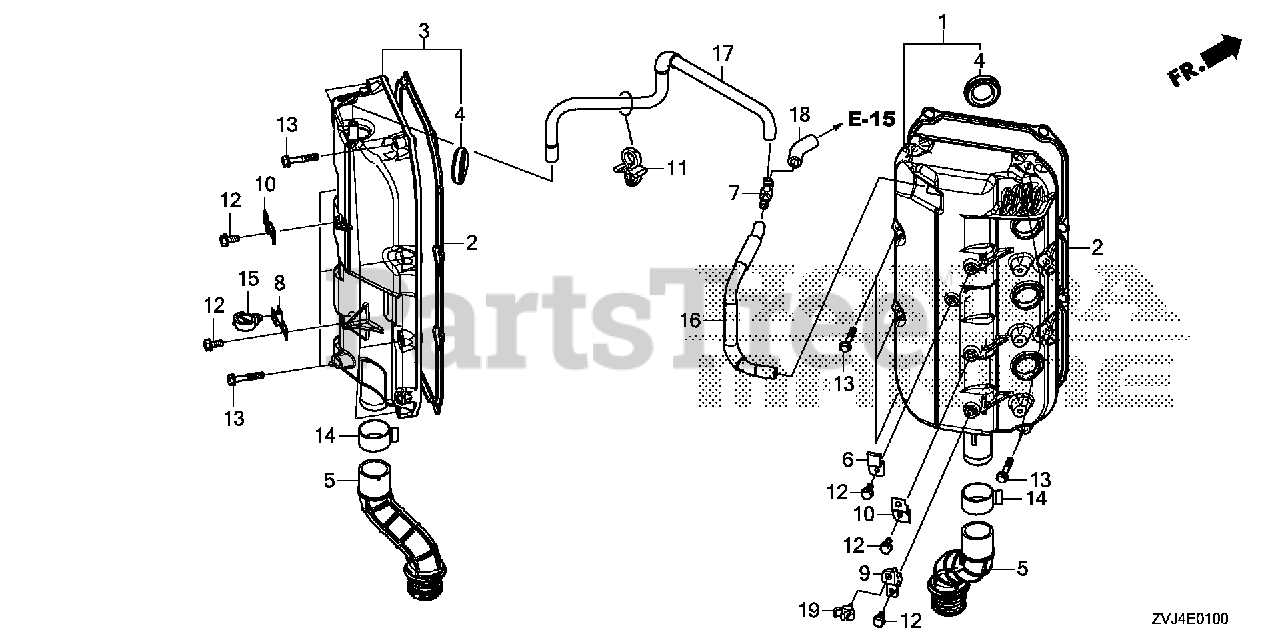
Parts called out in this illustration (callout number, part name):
1	COVER, CYLINDER HEAD *NH8* (R) (DARK GRAY)
2	GASKET, HEAD COVER
3	COVER, CYLINDER HEAD *NH8* (L) (DARK GRAY)
4	SEAL, SPARK PLUG TUBE (NOK)
5	TUBE, OIL
6	STAY B, FUEL STRAINER
8	BRACKET, FUEL PUMP CONNECTOR
9	BRACKET, CLIP B
10	BRACKET C, HARNESS CLIP
11	CLIP A, WIRE
12	BOLT, FLANGE (6X14) (CT200)
13	BOLT, FLANGE (6X35)
14	CLAMP, TUBE (D32.5)
15	CLIP, WIRE HARNESS (25MM)
16	TUBE A, BREATHER
17	TUBE B, BREATHER
18	TUBE C, BREATHER
19	CLIP D, WASHER TUBE
